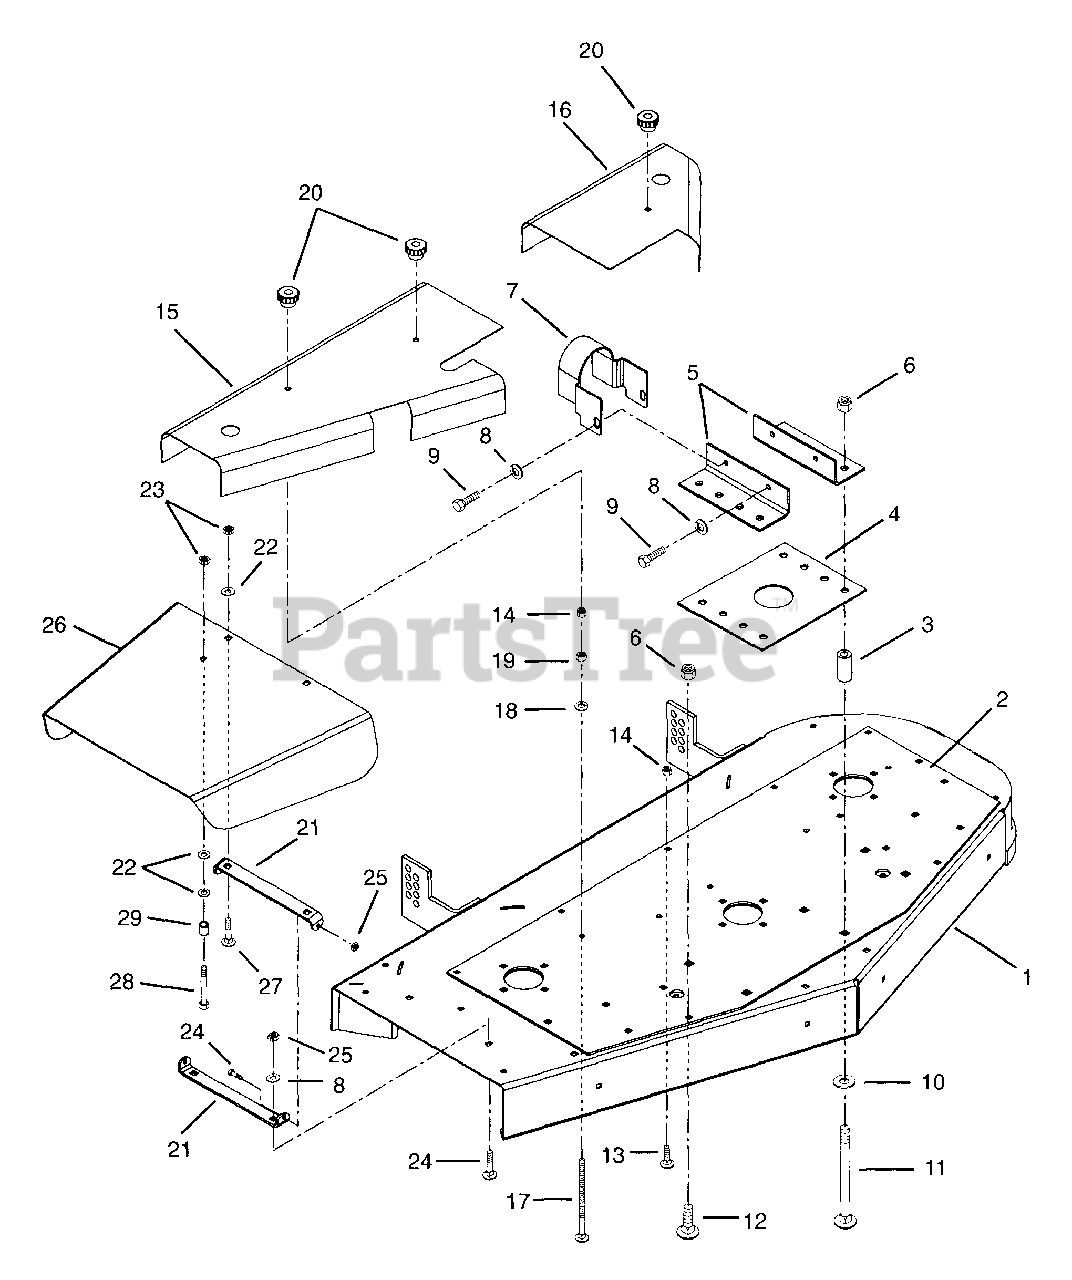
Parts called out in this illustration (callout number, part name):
1	Weldment, 50" Mower Deck
2	Plate, 50" Deck Reinforcing
3	Spacer .562 x 1.00 x 2.00
4	Plate, Gearbox Support
5	Bracket, Gearbox
6	Nut-Locking-Nylon .50-13
7	Shield, U-Joint
8	Washer-Lock .38 x .094
9	Bolt-Hex .38-16 x .875
10	Washer-Flat-Steel .531 x 1.062 x .095
11	Bolt-Hex .50-13 x 3.75 Grade 5
12	Bolt-Round Head Square Neck .50-13 x 1.00 Grade 5
13	Bolt-Round Head Square Neck .31-18 x .62
14	Nut-Locking-Nylon .31-18
15	Cover, Mower Belt Right Hand
16	Cover, Mower Belt Left Hand
17	Bolt-Round Head Square Neck .31-18 x 3.50 Grade 5
18	Washer-Lock .313 x .078
19	Nut Hex .31 18
20	Knob
21	Bracket, Chute
22	Washer-Flat-Steel .406 x .812 x .065
23	Nut-Locking-Nylon .38-16
24	Bolt-Hex .25-20 x .875
25	Nut-Locking-Nylon .25-20
26	Shield, Safety External 50" Mower
27	Bolt-Round Head Square Neck .38-16 x 1.00 Grade 5
28	Bolt-Hex .38-16 x 1.50 Grade 5
29	Bushing-Sleeve .407 x .625 x .750
